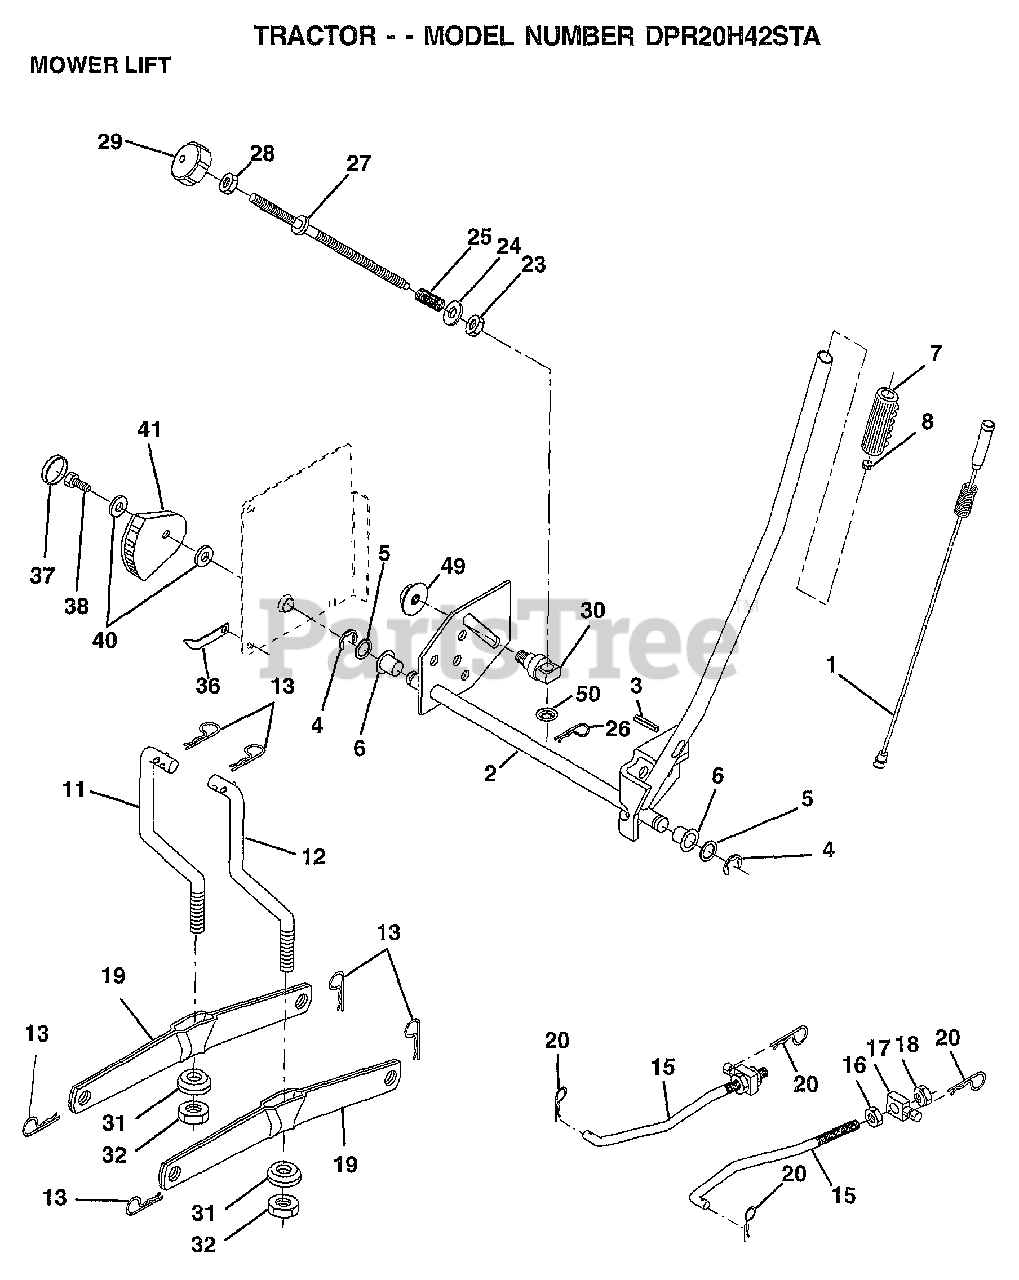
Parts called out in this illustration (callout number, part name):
1	WIRE ASM W.SPRING
2	"SHAFT ASM LIFT,RH"
3	PIN-GROOVE LT
5	WASHER
6	NYLON BEARING
7	GRIP HANDLE
8	BUTTON PLUNGER
15	LINK, FRONT
16	NUT
17	TRUNION
18	NUT.LK.W/WSH.1/2.
19	ARM SUSP REAR
20	RETAINER SPRING
23	NUT T
24	WASHER
25	SPRING T
26	RETAINER CLIP
28	NUT
29	KNOB INF 3/8-16
30	TRUNNION
31	BEARING PVT LH
32	NUT.CROWNLOCK.3/8
36	POINTER-INDICAT
37	"PLUG,HOLE"
38	SCREW
40	WASHER
41	INDICATOR HEIGHT
49	NUT.HXFLG.LOCK.
50	NUT PUSH M
